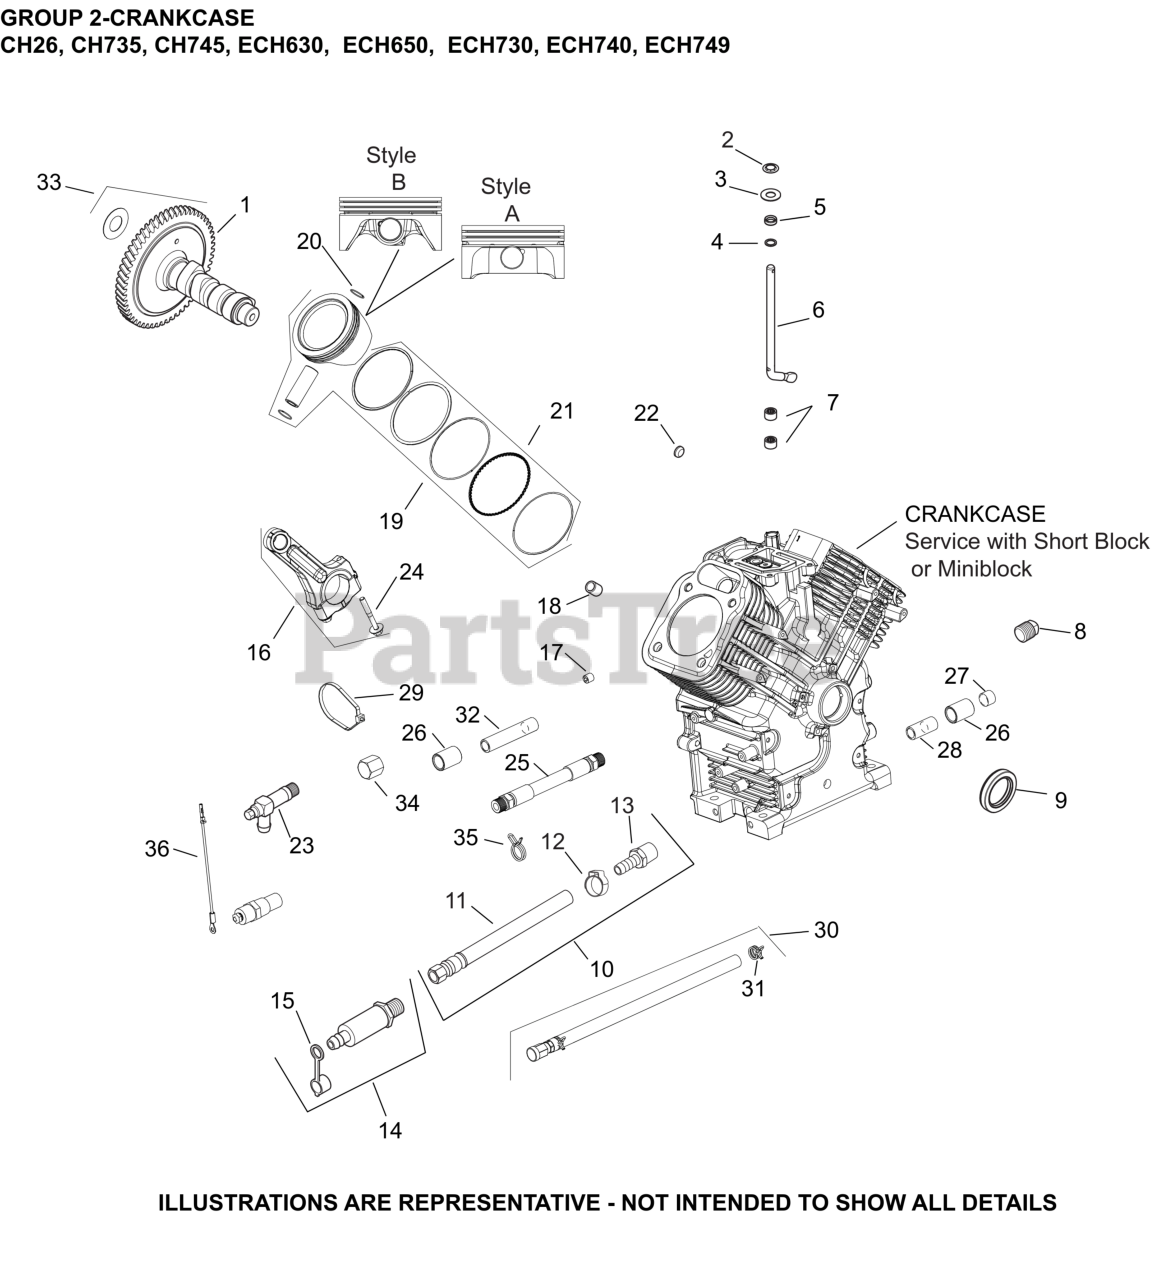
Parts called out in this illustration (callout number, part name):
1	KIT, CAMSHAFT
8	PLUG, SQ HD PIPE 3/8"
9	SEAL, OIL (HELIX LIP)
14	KIT, OIL DRAIN VALVE
15	CAP, OIL DRAIN VALVE
16	ROD, ASSEMBLY CONNECTING
18	PIN, LOCATING
19	KIT,PSTN/RNG STYLE B(STD)
19	KIT,PSTN/RNG STYLE B(.08)
19	KIT,PSTN/RNG STYLE B(.25)
19	KIT,PSTN/RNG STYLE B(.50)
20	RETAINER, PISTON PIN
21	RING SET(STD)STYLE B-1.2mm Tp RING THICK
21	RING SET(.08)STYLE B-1.2mm RING THICK
21	RING SET(.25)STYLE B-1.2mm Tp RING THICK
21	RING SET(.50)STYLE B-1.2mm Tp RING THICK
22	PLUG, CUP
24	KIT, ROD BOLTS-(#25086677S)
32	NIPPLE, PIPE
